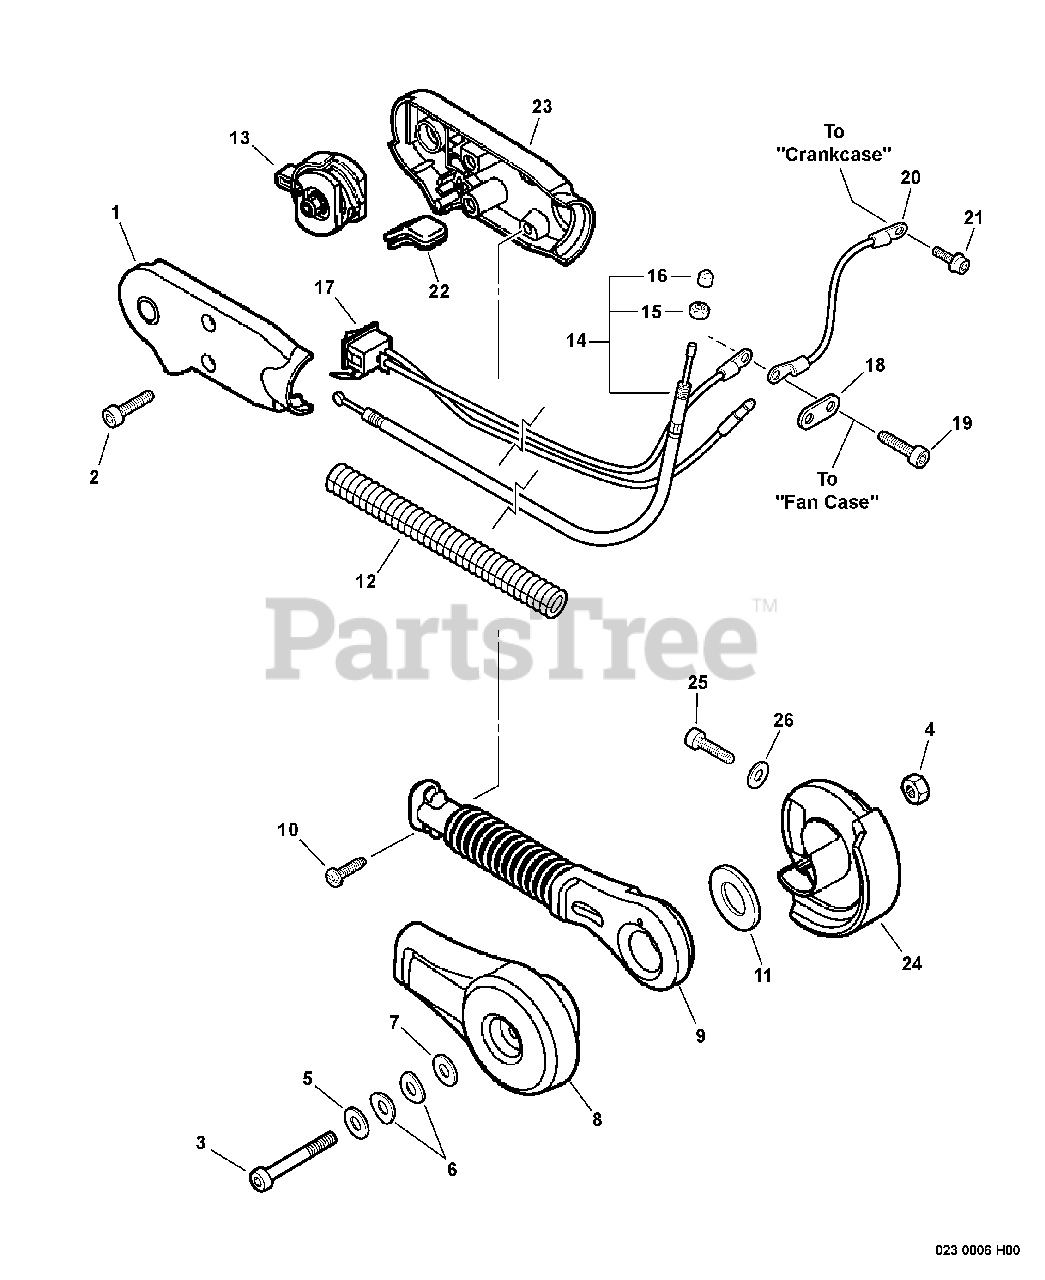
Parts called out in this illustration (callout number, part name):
1	HANDLE, CONTROL - LEFT
2	SCREW - 5X14
3	BOLT - 6
4	LOCKNUT - 6
5	WASHER - 6
6	WASHER - SPRING
7	WASHER - 6
8	BRACKET, ARM - OUTER
9	ARM, THROTTLE CONTROL
10	SCREW - 5X20
12	TUBE, PROTECTIVE - CORRUGATED
13	CONTROL, THROTTLE
14	CABLE, THROTTLE
15	LOCKNUT - 6
16	CAP, DUST
17	SWITCH, IGNITION
19	SCREW - 5X16
20	LEAD - GROUND
21	SCREW - 5X8
23	HANDLE, CONTROL - RIGHT
24	BRACKET, ARM - INNER
25	SCREW - 5X20 -- TAPPING
26	WASHER - 5
